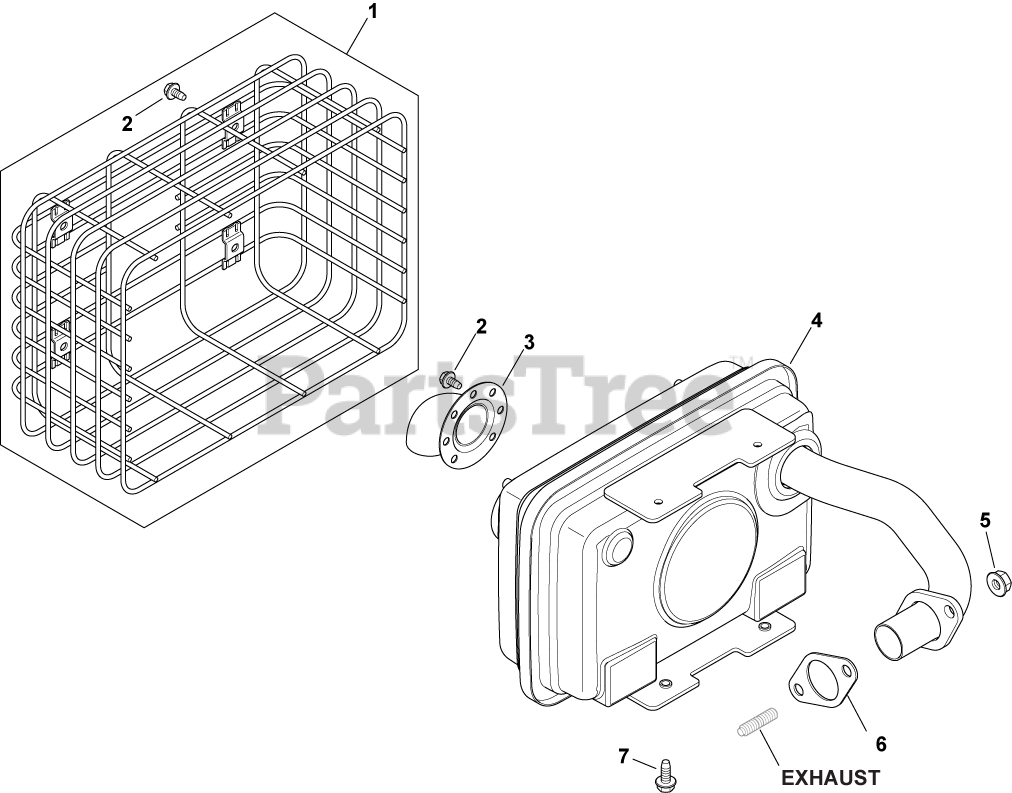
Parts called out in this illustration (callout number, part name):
1	KIT, MUFFLER GUARD
2	SCREW, FLG THD FRM M5X.8X10
3	DEFLECTOR, EXHAUST - USE 12 265 09-S
5	NUT, FLG M8X1.25
6	GASKET, EXHAUST MANIFOLD
7	SCREW,FLG THD FRM M6X1.0X16-(#25086397S)
